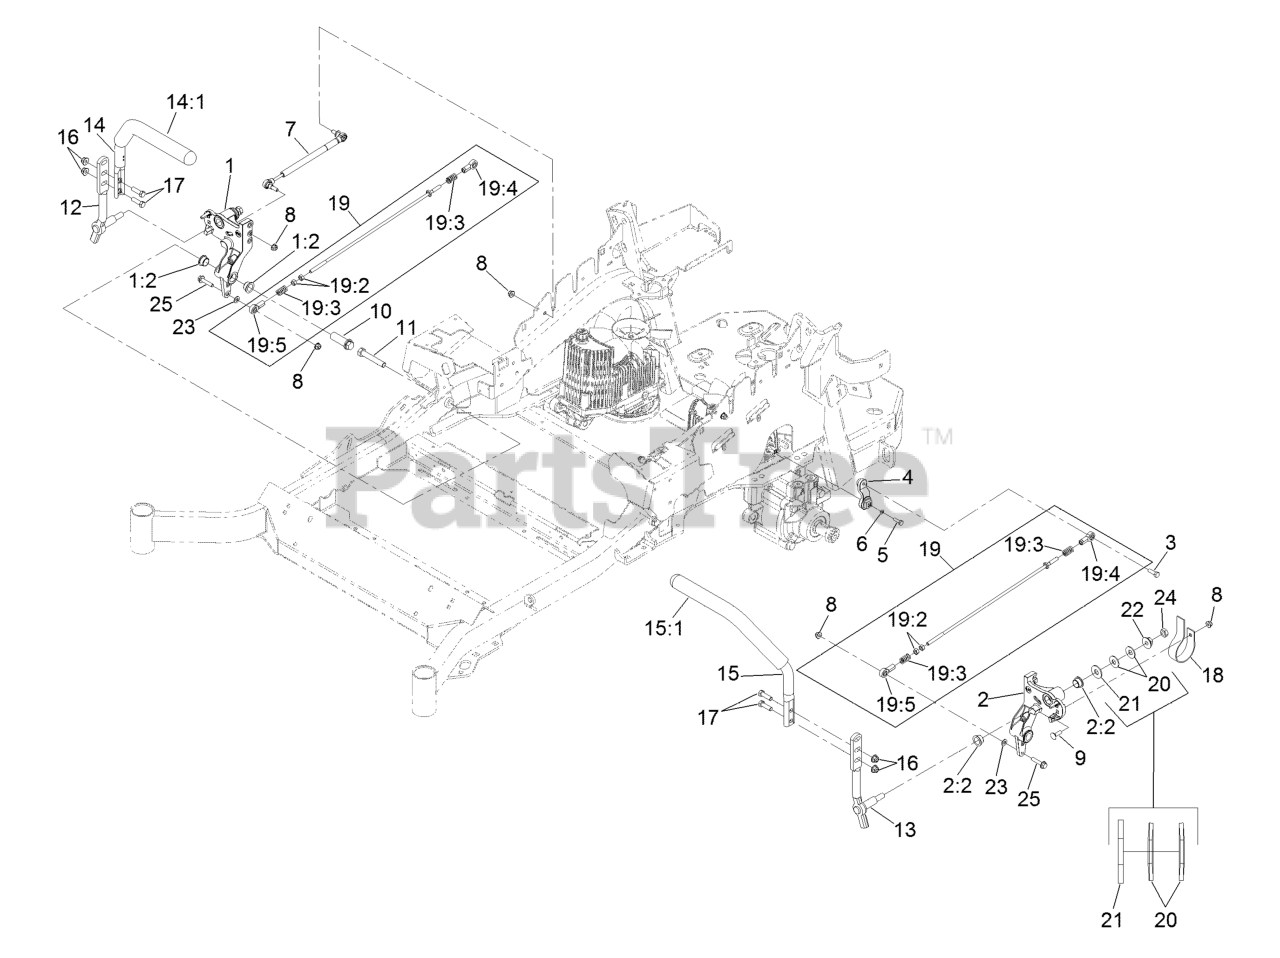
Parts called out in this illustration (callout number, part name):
1	RH MOTION CONTROL AND BUSHING ASM
1:2	BUSHING-FLANGE
2	LH MOTION CONTROL AND BUSHING ASM
2:2	BUSHING-FLANGE
3	SCREW-HH, THREAD LOCKING
4	ARM-CONTROL, PUMP
5	SCREW-HH
6	WASHER-SPRING
7	DAMPER-CONTROL, MOTION
8	NUT-HF, NI
9	BOLT-CARR
10	HUB-THREADED
11	SCREW-HH
12	LEVER-CONTROL MOTION, RH
13	LEVER-CONTROL MOTION, LH
14	RH STEERING HANDLE ASM
14:1	GRIP-LEVER, CONTROL
15	LH STEERING HANDLE ASM
15:1	GRIP-LEVER, CONTROL
16	NUT-HF, NI
17	SCREW-HH
18	SPRING-LEAF
19	PUMP LINKAGE REAR ASM
19:2	NUT-HEX
19:3	SPRING-COMPRESSION
19:4	BALLJOINT-LH
19:5	BALLJOINT-RH
20	WASHER-SPRING
21	WASHER-FLAT
23	WASHER-PLAIN
24	NUT-JAM
25	SCREW-HHF
